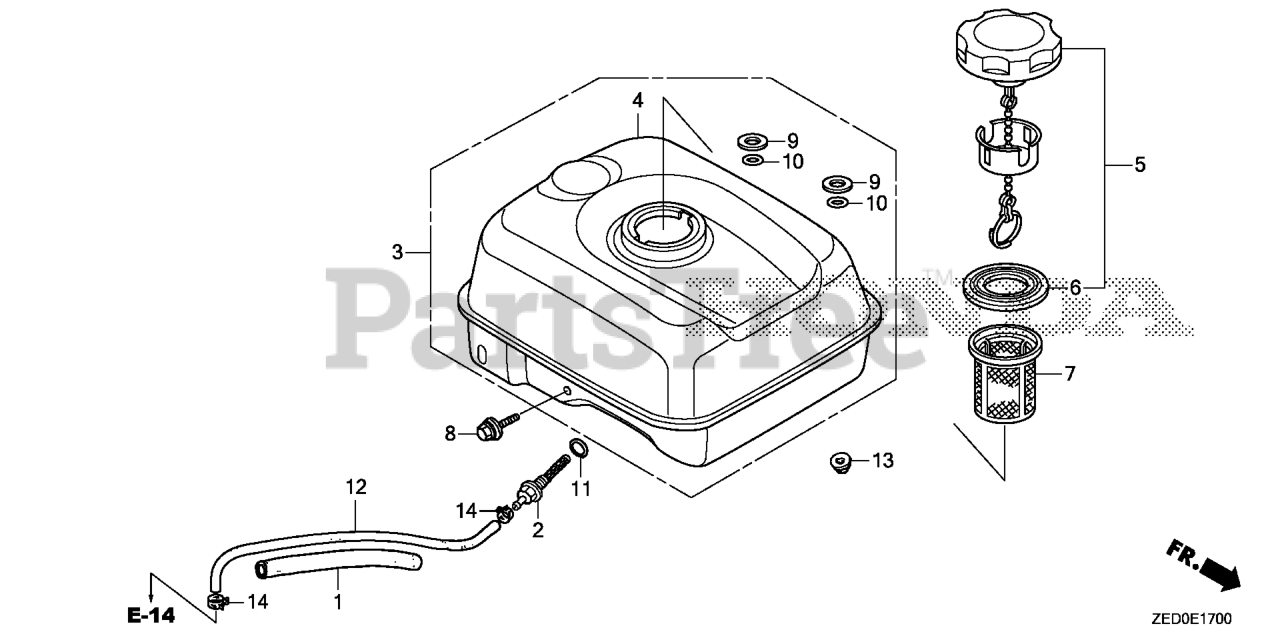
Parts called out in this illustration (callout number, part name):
1	RUBBER, SUPPORTER (107MM)
2	JOINT, FUEL TANK
3	TANK ASSY., FUEL *NH1* (BLACK)
5	CAP, FUEL FILLER
6	GASKET, FUEL FILLER CAP
6	GASKET, FUEL FILLER CAP (39X62X3) (TOUYOUSYA)
7	FILTER, FUEL (FROM 1204807)
8	BOLT, FLANGE (6X29)
9	WASHER, TANK CUSHION
10	O-RING (5.5X1.5)
11	O-RING (14MM) (ARAI) Use up to Engine SN 2949254.
12	TUBE, FUEL (4.5X145)
13	NUT, FLANGE (6MM)
14	CLIP, TUBE (D8)
